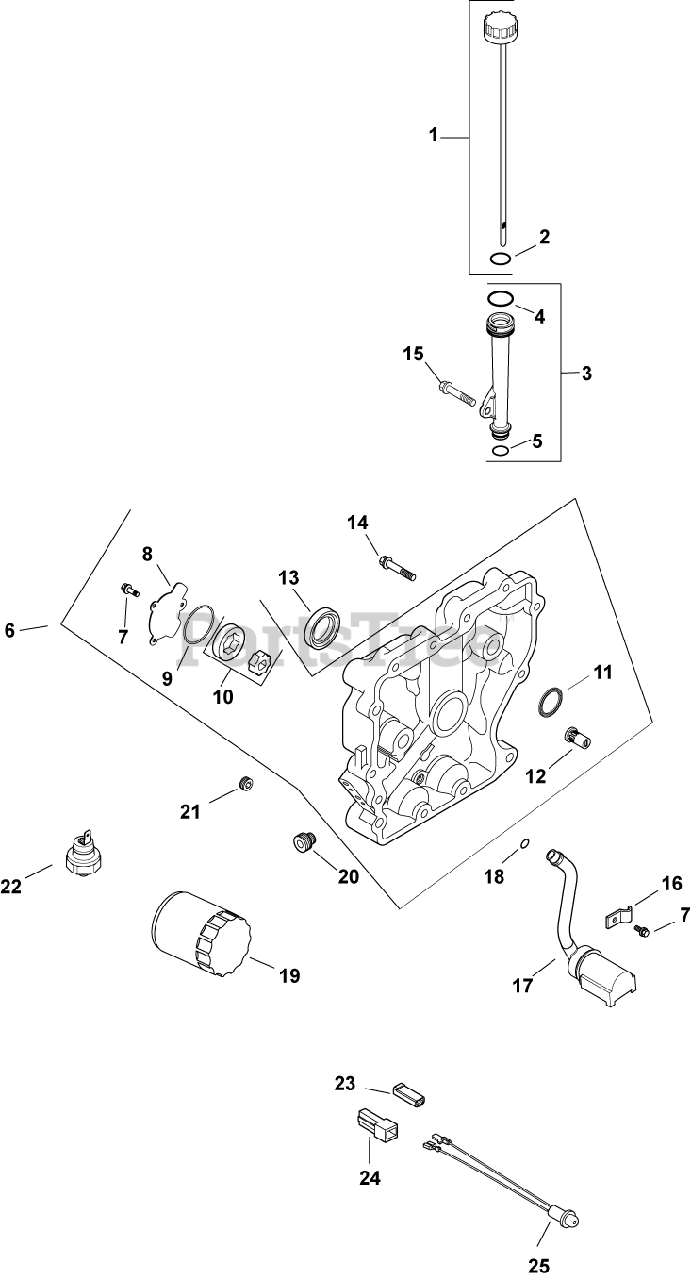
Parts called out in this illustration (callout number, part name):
1	KIT, OIL FILL CAP ASSEMBLY
2	O-RING, UPPER OIL FILL TUBE
3	KIT, OIL FILL TUBE - USE 12 755 113-S
4	O-RING, UPPER OIL FILL TUBE
6	PLATE, CLOSURE & BEARING
7	SCREW,FLG THD FRM M5X0.8X16-(#25086398S)
8	COVER, OIL PUMP
9	O-RING (1.78" DIA)
10	PUMP ASSEMBLY, OIL
11	BEARING, CRANKSHAFT
12	VALVE, OIL PRESSURE RELIEF
13	SEAL, OIL
14	SCREW, FLG M8X1.25X45
15	SCREW, FLG M8X1.25X50
17	KIT, OIL PICK-UP
18	O-RING (.5" DIA)
19	OIL FILTER
20	NIPPLE, OIL FILTER
21	PLUG, CTSK PIPE 1/8"
22	SENSOR, OIL PSI
23	CONNECTOR (1 CONTACT)
24	CONNECTOR
